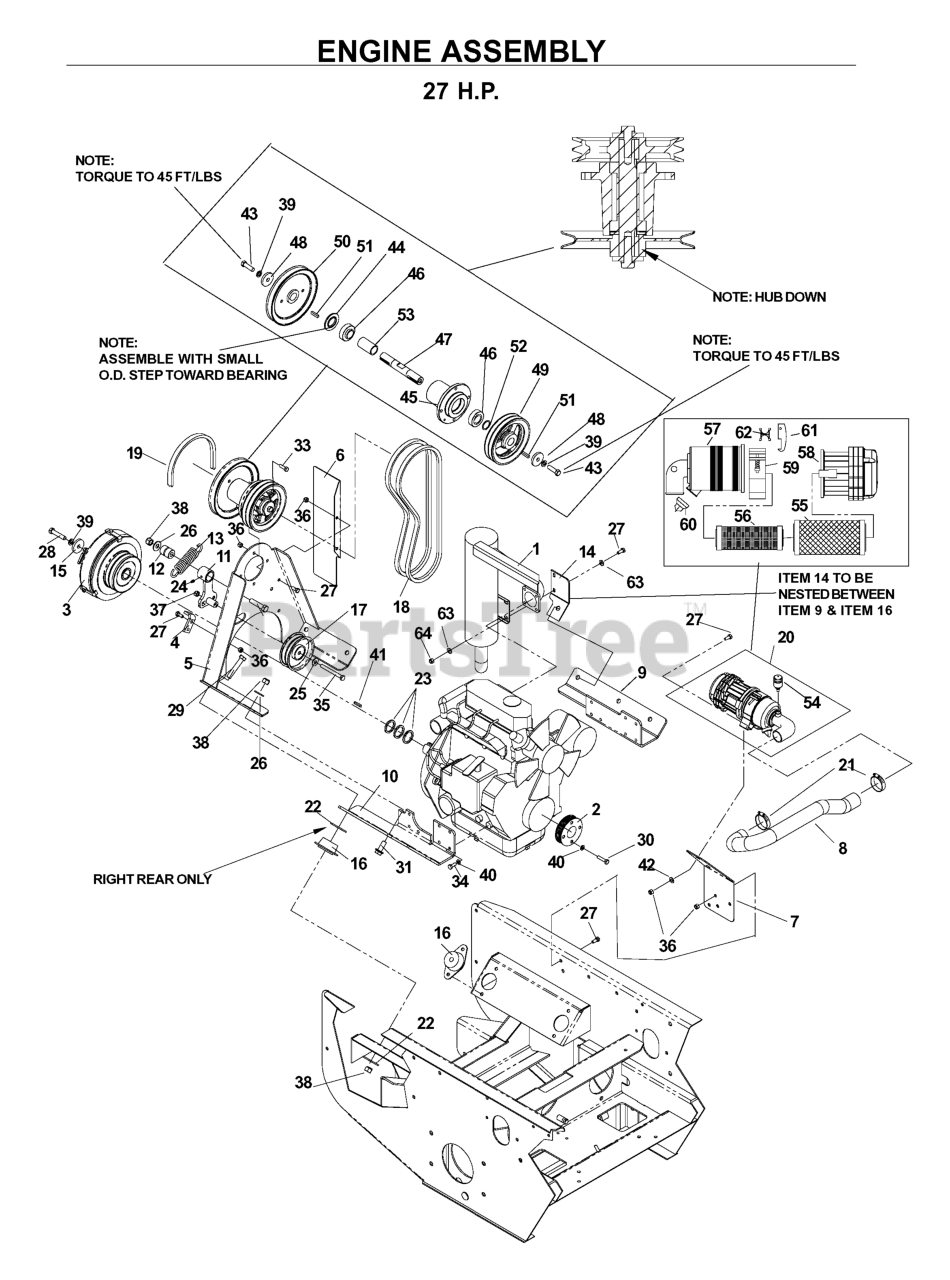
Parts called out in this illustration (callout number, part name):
1	MUFFLER
2	ENGINE SHEAVE
3	CLUTCH
4	RESTRAINT
5	JACKSHAFT MOUNT WELDMENT
6	HEAT SHIELD
7	MOUNTING BRACKET
8	AIR FILTER HOSE
9	ENGINE MOUNT-LT
10	ENGINE MOUNT-RT
11	ARM WELDMENT
14	MUFFLER MT BLACK PAINTED
15	SPINDLE WASHER
17	IDLER, PRIMARY
18	ENGINE BELT, PRIMARY
19	ENGINE, BELT MULE
20	AIR FILTER ASSY - NON-TURBO
22	ISOLATOR WASHER
23	BUSH 1-1/8 X 10 GA ZD
24	ZERK
25	WASHER 3/8 SAE FLAT
26	WASHER 1/2 FLAT
27	HCS 5/16C X 3/4
28	BOLT 7/16F X 2 1/2
29	HCS 1/2C X 2 3/4
30	HTB M8-1.125 X 25MM
31	HCS 1/2C X 1 1/4 SERRATED HEAD
32	HEX SCREW 1/2-13 X 2.5" GR 5
33	HCS 5/16C X 1
35	HCS 3/8-16 X 3-1/2 GR5 ZD
36	NUT 5/16 NYLOC
37	NUT 3/8-16 NYLOC
38	NUT 1/2-13 HEX NYLOC ZD
39	WASHER 7/16 LOCK
40	WASHER.LOCK.HVY.HLCL.SPR.5/16
41	KEY 1/4" SQ X 1 7/8"
42	WASHER 5/16 FLAT
43	HCS 7/16F X 1 1/2
44	COMBO SPACER
45	HOUSING, DIE CAST
46	BEARING
48	SPINDLE WASHER
51	KEY 1/4 SQ X 1 1/8
52	BUSHING.MACHINE.18.GAUGE
55	AIR FILTER
56	SAFETY ELEMENT
57	BODY - 90 DEG
58	PRECLEANER ASM
59	MOUNTING BRACKET
63	WASHER, 3/8 DISC SPRING SPEC
64	NUT 5/16C WHIZ
539106327	STUB SHAFT
539109177	MANIFOLD GASKET
